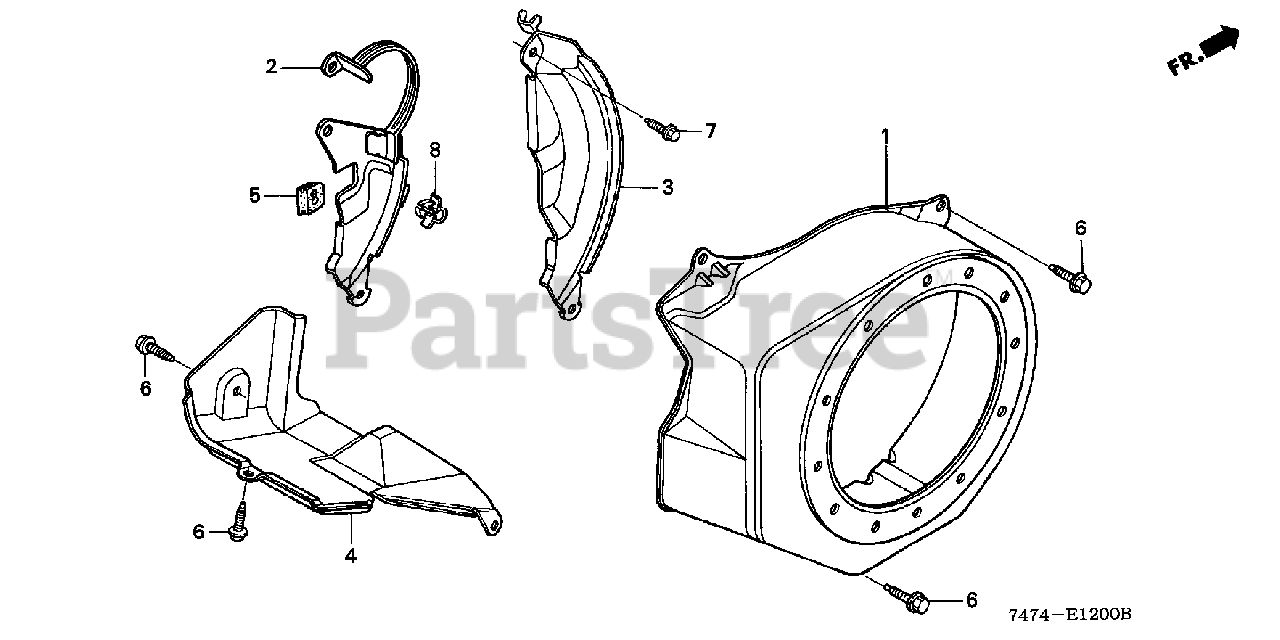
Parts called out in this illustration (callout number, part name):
1	COVER, FAN *R8* (BRIGHT RED)
3	PLATE, SIDE (STD)
4	SHROUD
6	BOLT, FLANGE (6X12) (CT200)
7	BOLT, FLANGE (6X20) (CT200)
